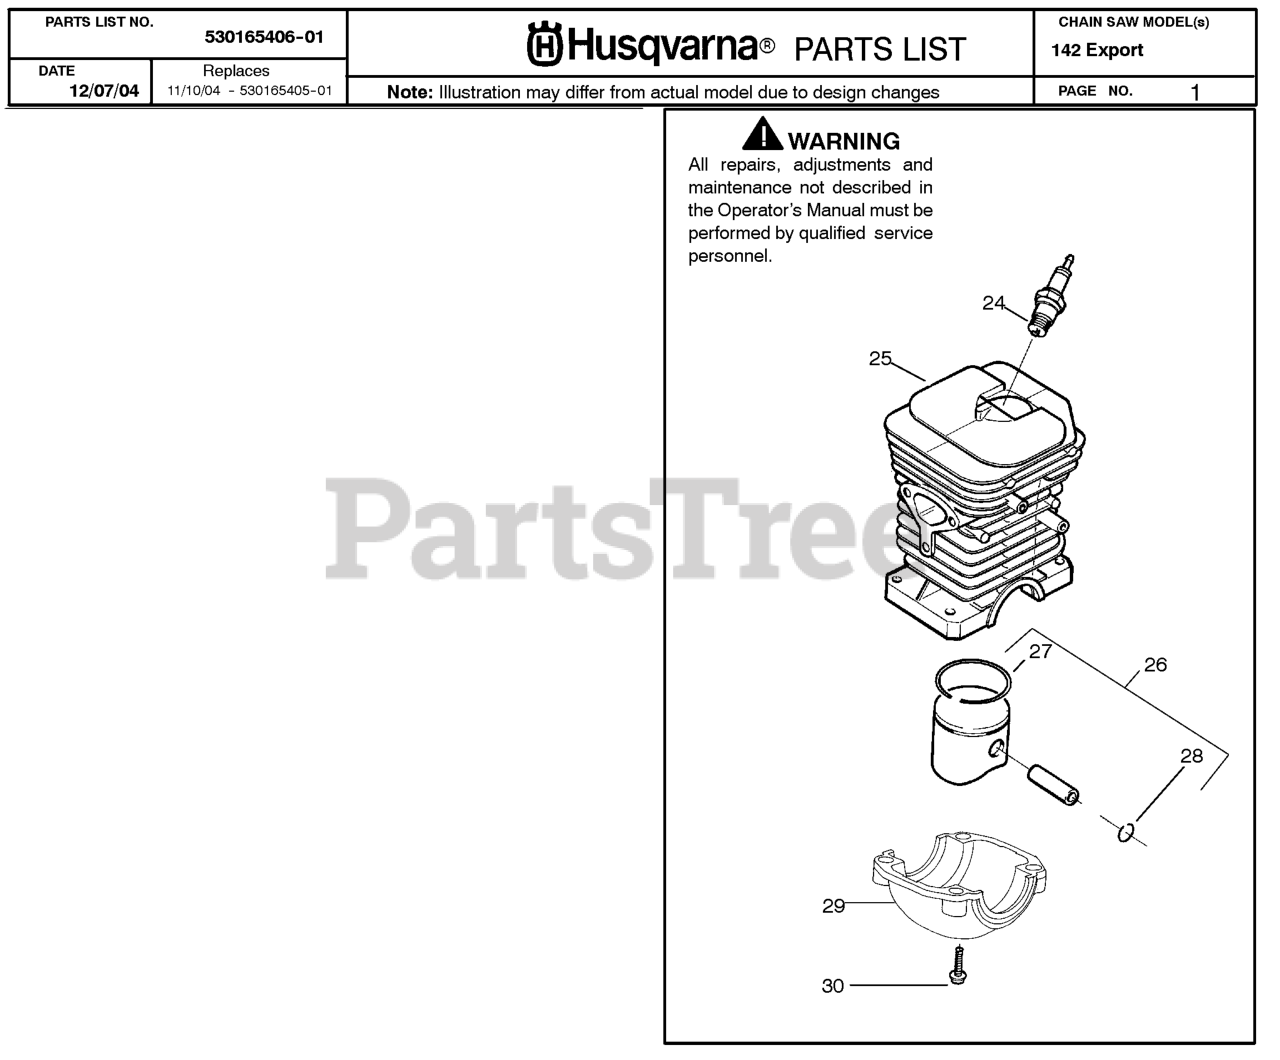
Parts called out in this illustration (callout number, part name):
24	Spark Plug (RCJ--7Y)
25	CYLINDER ASSY/141
26	KIT-PISTON
27	PISTON RING HV41
28	C-CLIP,PSTN PIN 36/41
29	CAP-CRANKSHAFT
30	SCREW-M5-0.8 X 25MM(TAP)
530031135	SCRENCH
